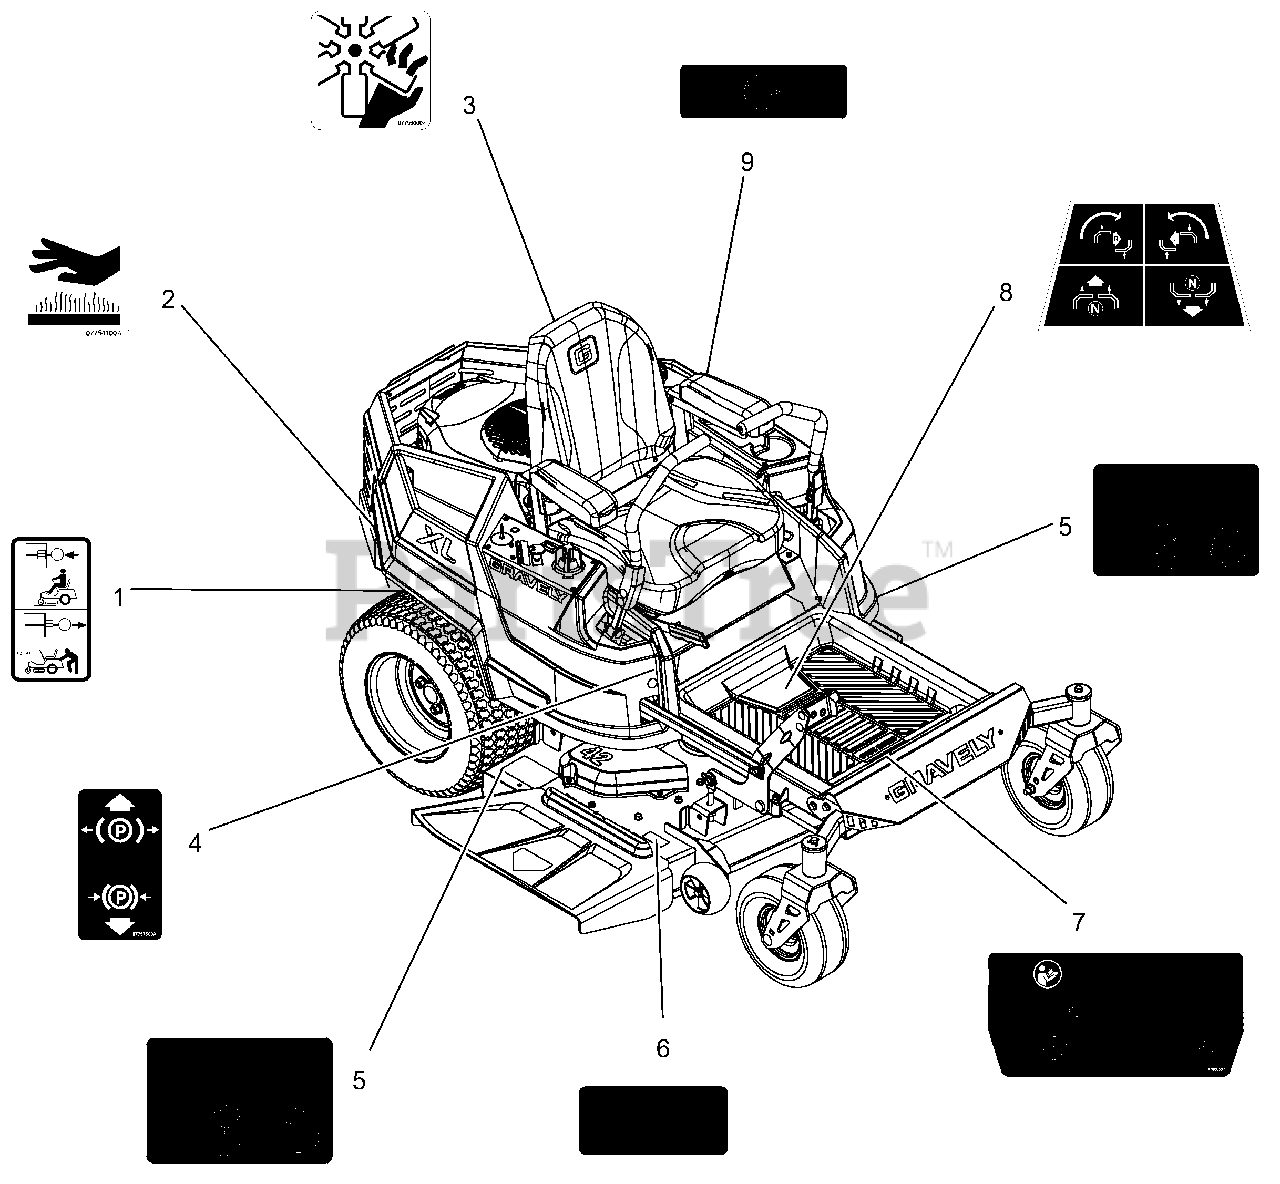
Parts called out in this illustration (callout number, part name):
1	DECAL, TRANSMISSION DISCONNECT
2	DECAL, HOT SURFACE
3	DECAL, DANGER FAN
4	DECAL, PARKING BRAKE LEVER
5	DECAL, SAFETY - MOWER DECK
6	DECAL, SAFETY - DECK GUARDING
7	DECAL, MAIN SAFETY
8	DECAL, STEERING
9	DECAL-FUEL, WARNING
